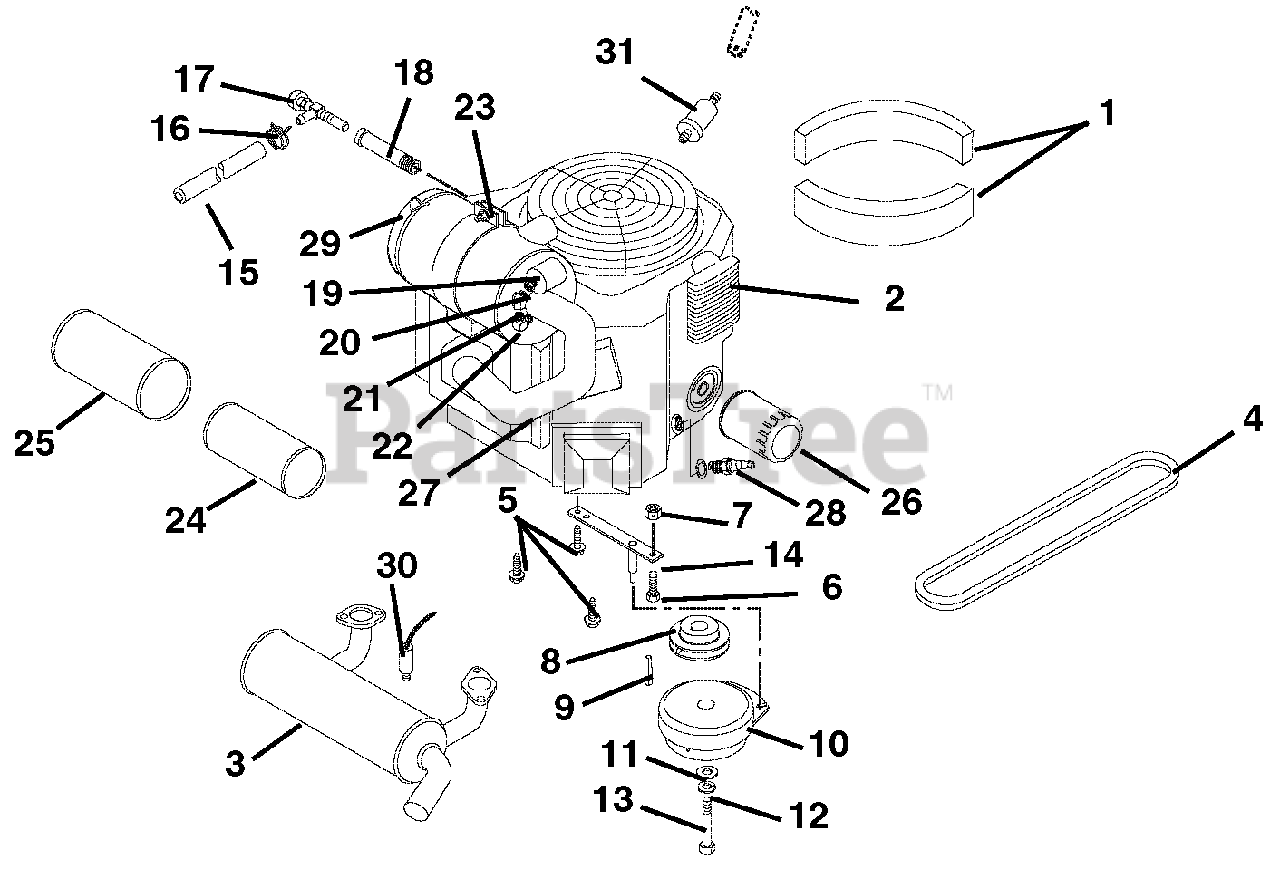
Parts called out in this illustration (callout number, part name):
1	Seal, Foam
2	Engine, Kohler 28HP EFI (048)
3	Muffler, Kohler EFI (048)
4	Belt, Poly-V
5	Screw, Tapping Hex Washer Head .38-16 x 1.00
6	Bolt, Hex .31-18 x 1.75 Grade 5
7	Nut, Locking Top Flange .31-18
8	Sheave, Poly V 1.127 x 3.25
9	Key, Square .25 x 1.00 x .25
10	Clutch, Electric
11	Washer, Flat Steel .515 x 1.625 x .250
12	Washer, Locking .44 x .109
13	Bolt, Hex .44-20 x 3.00 Grade 5
14	Anchor, Clutch
15	Gas Line, Bulk .25 ID (045, 046, 047, 049, 052, 053)
16	Hose, Clamp
17	Cock, Oil Drain
18	Adapter, Oil Drain
19	Filter Minder (047, 048, 052, 053)
20	Nipple, .125 NPT (047, 048, 052, 053)
21	Elbow, 45 Degree .125 NPT (047, 048, 052, 053)
22	Elbow, Adapter 90 Degree, Brass, .125 x .125 (047, 048, 052, 053)
23	Bracket, Air Cleaner Mount
24	Element, Inner Safety
25	Element, Outer Primary
26	Oil Filter (047, 048, 052, 053)
27	Hose, Air Intake (047, 048, 052, 053)
28	Spark Plug (047, 048, 052, 053)
29	Assembly, Air Cleaner
30	Sensor, Oxygen (048)
31	Fuel Filter (045, 046, 049)
